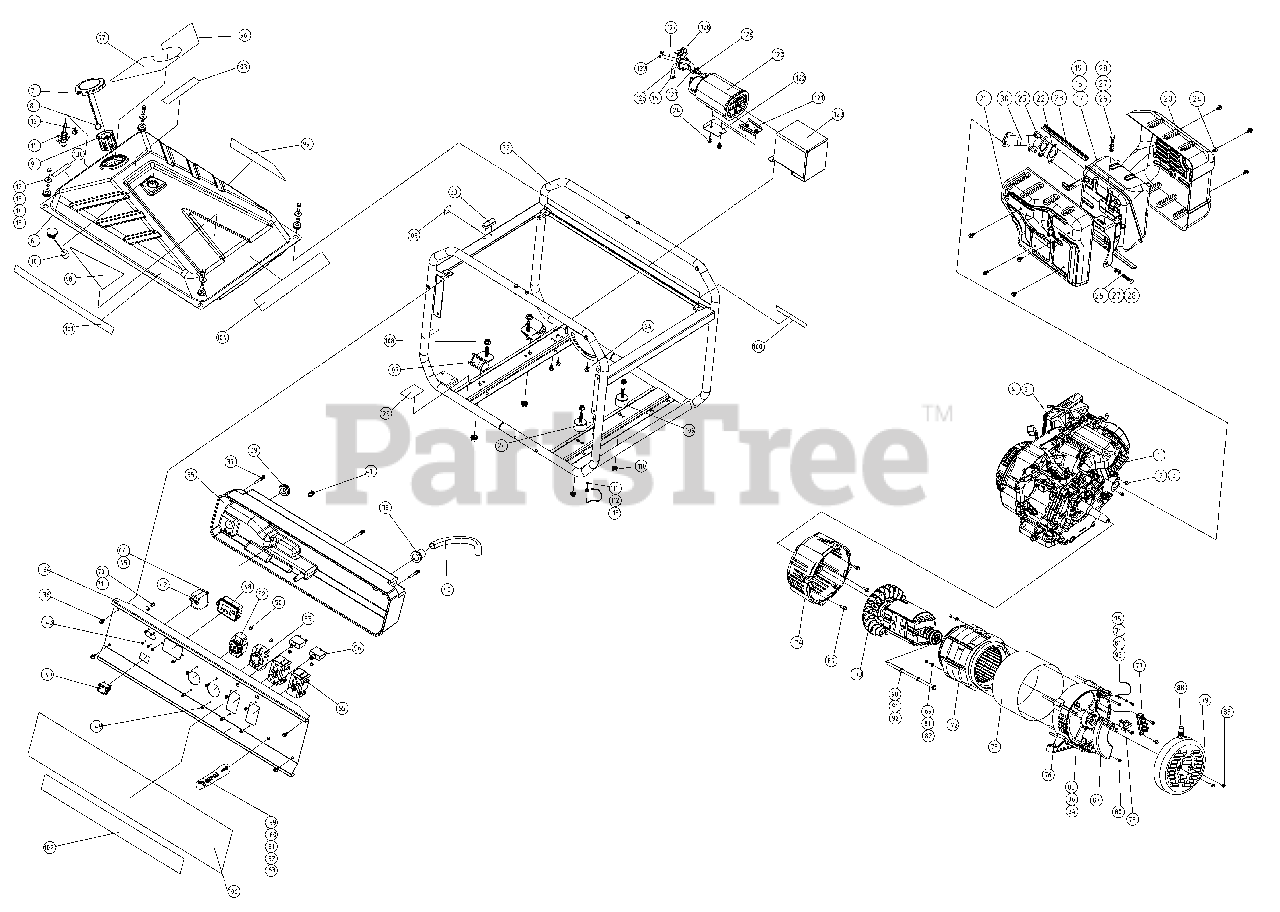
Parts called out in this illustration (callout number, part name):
1	CH440TF E3 KPP
2	GASKET, MUFFLER
3	NUT USE 25 086 240-S
4	LINE, FUEL (10"-CUT TO LENGTH)
5	CLAMP, FUEL LINE
6	TANK, FUEL
7	CAP ASSEMBLY - FUEL TANK (EPA)
8	RETAINER, TANK CAP PULL RING
9	FILTER , FUEL TANK
10	GUAGE, FUEL LEVEL ASSEMBLY
11	VALVE,FUEL SHUT OFF
12	SCREW, BOLT GB 5787-M6X20
13	MOUNT, FLAT GASKET GB/T 5287-6
14	SPACER, FUEL TANK BUSHING
15	SPACER, INNER RING
16	CLAMP, FUEL LINE 6
20	COVER, MUFFLER FRONT
21	COVER, MUFFLER BACK
23	MOUNT, RUBBER GASKET
24	SCREW, BOLT M6X12
25	SCREW, BOLT M8X22
26	SCREW, BOLT M8X20
27	WASHER, FLAT GASKET 8
28	WASHER, SPRING 8
29	SCREW, BOLT L35
30	MANIFOLD, MUFFLER PIPE ASSEMBLY
31	SPACER, MUFFLER BUSHING
33	DAMPER, HANDLE DAMPING PAD
34	PANEL (PRO7.5E)
36	SCREW, BOLT GB5789-M6X12
37	SCREW M5X45
38	GROMMET, POWER CORD SHEATH
39	GROMMET 16MM
40	SLEEVE BRAIDED SLEEVE 1
41	STRAP, CABLE TIES 3.2X120 (WHITE)
43	SCREW, M3X6
44	SCREW GB818-M4X8
45	WASHER, SPRING GB93-4
48	DIGITAL DISPLAY METER
49	SCREW M4X12
52	L 14-30 SOCKET
53	RECEPTACLE, NEMA L5-30R SOCKET
54	BREAKER, CIRCUIT 20A
55	RECEPTACLE, GFCI 20A/125V NEMA 5-20OR
56	BREAKER, CIRCUIT 20A
59	SCREW, BOLT M6X25
61	WASHER, PLATE GASKET 6
62	WASHER, SPRING GASKET 6
70	SCREW M5X12
71	WASHER, SPRING GB 93-5
72	STATOR ASSEMBLY
73	ROTOR ASSEMBLY (PRO7.5E)
76	CAP, BACK COVER
77	BOARD ASSEMBLY, PATCH
78	BRUSH, CARBON ASSEMBLY
80	SCREW, BOLT GB 5787-M5X16
81	WASHER, PLATE GT/T 95
82	SCREW, BOLT M5X205
83	SCREW, BOLT M5X10
84	SCREW BOLT M6X180
85	WASHER, PLATE GASKET 6
86	WASHER, SPECIAL SPRING 6
87	RECTIFIER AVR (PRO7.5E)
88	SLEEVE, MOTOR RUBBER SHEATH
89	SCREW BOLT 3/8-16X27MM
90	BOLT 5/16-24X222MM
92	WASHER, SPRING
93	BOLT GB/T 5783-M5X10
95	WIRE, 10GA WHITE
96	DECAL, TANK BRAND, LEFT
100	DECAL, HOT_EXHAUST
101	CPSC DECAL_5.2
102	DECAL, OPERATING_PROCEDURE
104	DECAL, GENERATOR_WARNING
105	FUEL SWITCH DECAL
107	MOUNT, ENGINE ISO
109	MOUNT, RUBBER FOOT
111	GROUND WIRE
112	SPACER, FLOWER SHAPED GASKET
120	CARBON CANISTER
121	PLATE, CARBON TANK HOLDER (W/NUT)
122	PLATE, CARBON TANK HOLDER (NONE NUT)
124	HOSE, FUEL PIPE 2
125	FUEL HOSE, LOW PERMEATION
126	CLAMP, FUEL PIPE 5
127	CLAMP, FUEL PIPE 7
128	STRAP, CABLE TIES 7.7X150 8
